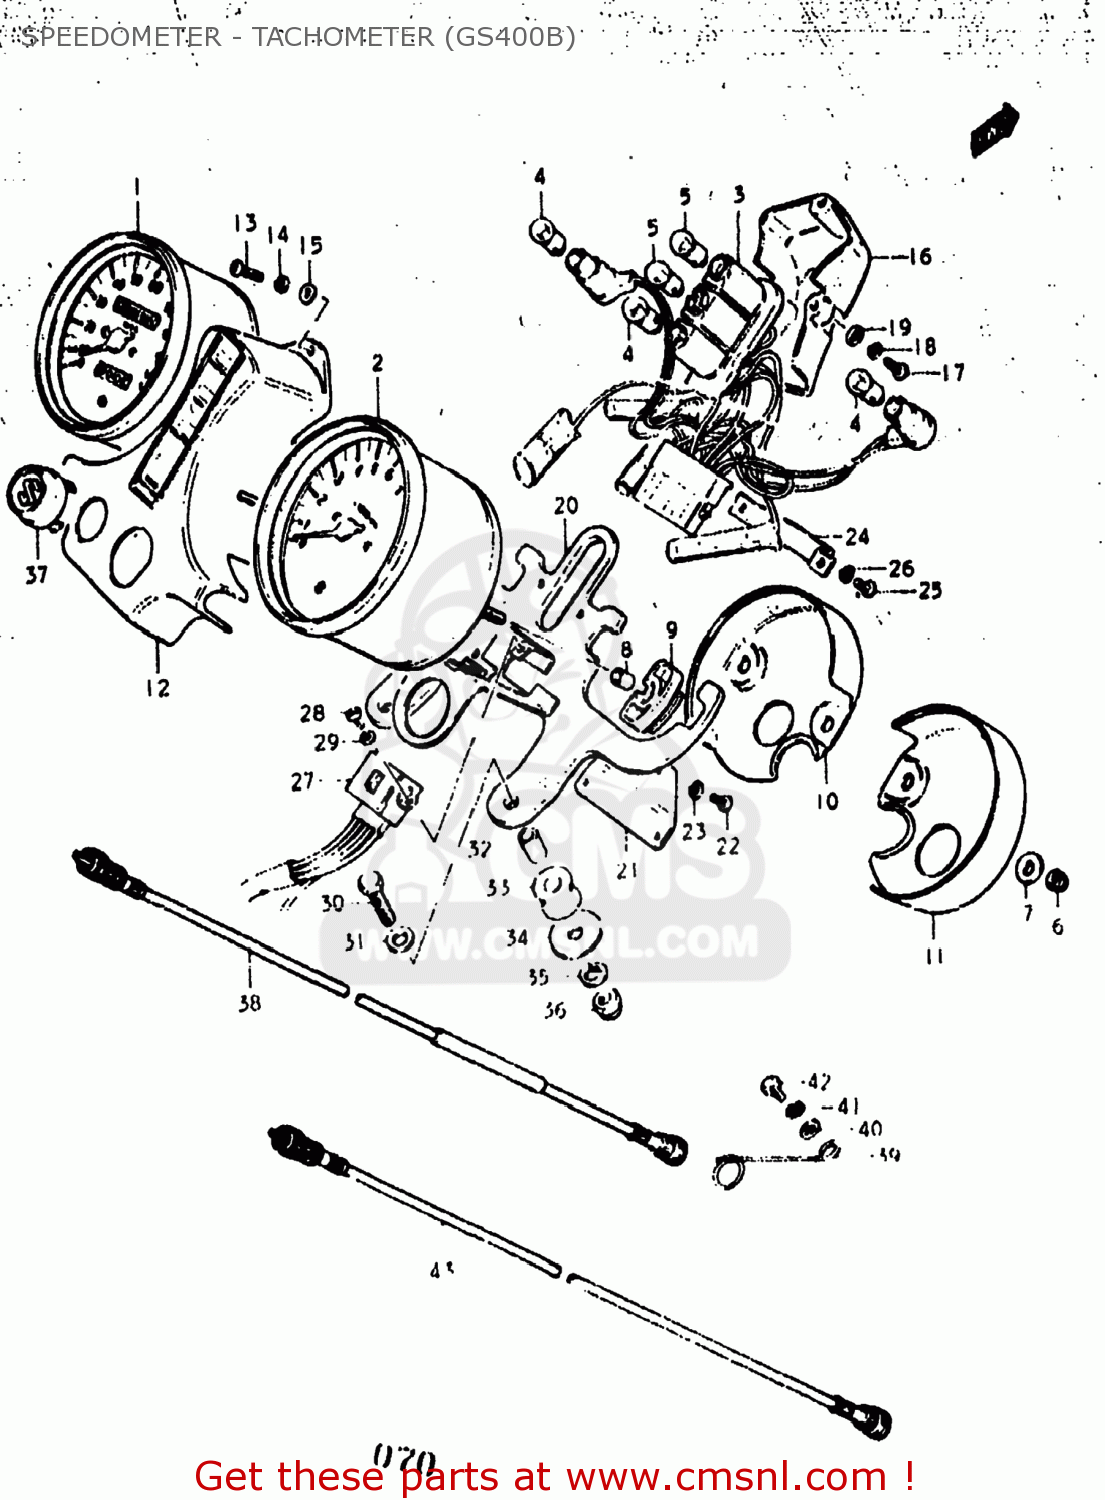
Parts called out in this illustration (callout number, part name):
1	SPEEDOMETER ASSEMBLY
2	TACHOMETER
3	SOCKET,METER
4	BULB(12V3.4W,STANLEY,A72A)
5	BULB(12V1.7W,A71A)
6	NUT
7	WASHER,METER
8	SPACER,METER
9	CUSHION,METER
10	PANEL,METER
11	COVER,METER,UNDER
12	CASE,PILOT BULB
13	SCREW
14	WASHER,PILOT UNDER CASE
15	WASHER
16	COVER
17	SCREW(4X16)
18	WASHER,PILOT UNDER CASE
19	WASHER
20	BRACKET,METER
22	SCREW
23	LOCK WASHER
24	HOLDER,COUPLER
25	SCREW
26	LOCK WASHER
27	SENSOR,SPEED
28	SCREW
29	LOCK WASHER
30	BOLT
31	WASHER
32	SPACER (6.1X9X9)
33	CUSHION,METER
34	WASHER (6.5X20X1.2)
35	LOCK WASHER
36	NUT
37	CAP,SPEED WARNER LAMP HOLE
38	CABLE ASSEMBLY,SPEEDOMETER
39	GUIDE,SPEEDOMETER CABLE
40	WASHER 6MM
41	LOCK WASHER
42	BOLT
43	CABLE ASSEMBLY,TACHOMETER
